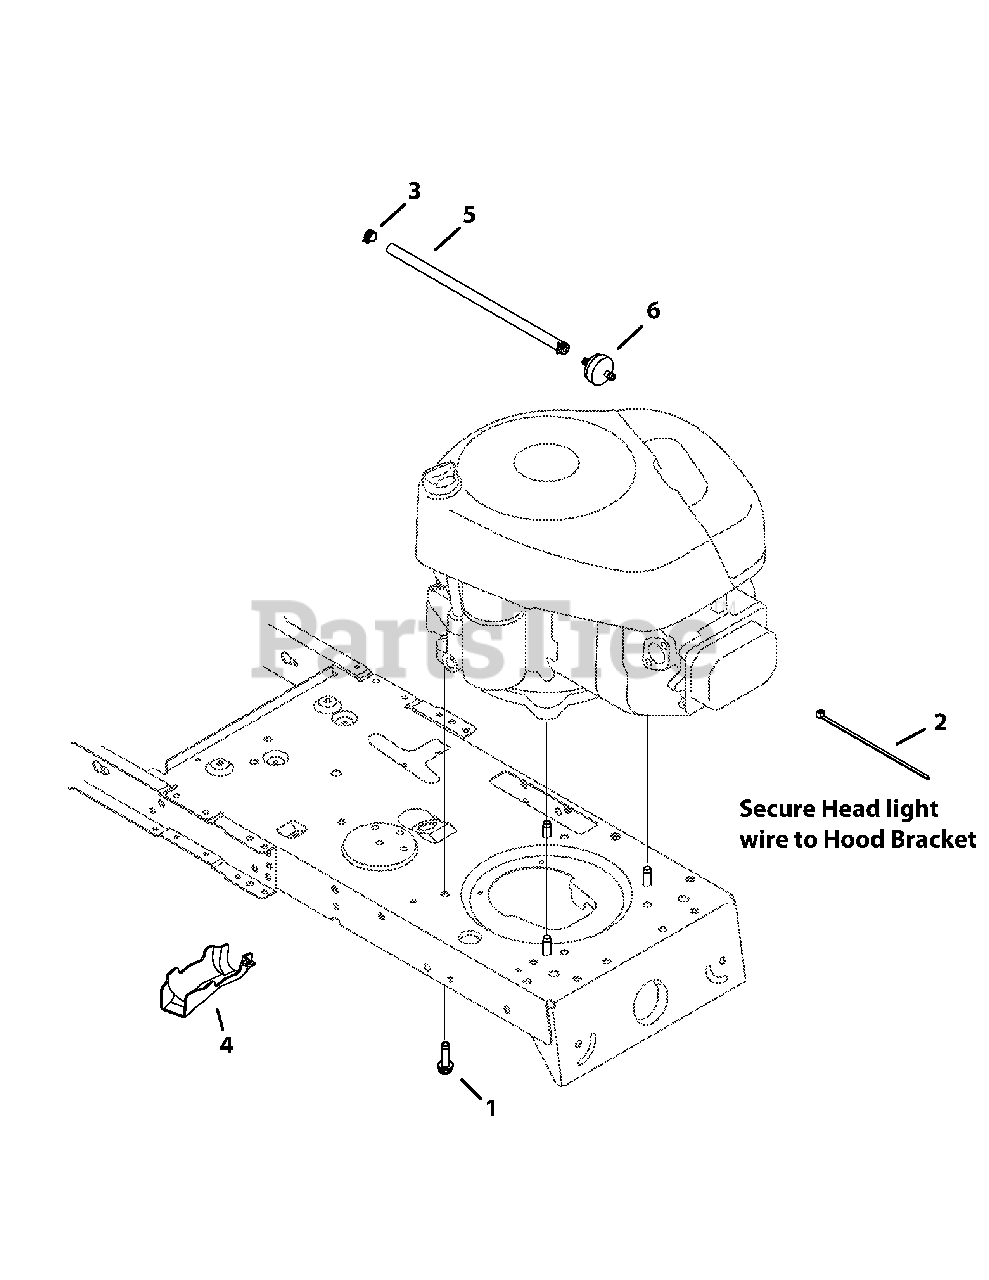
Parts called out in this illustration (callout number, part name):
1	Screw, 3/8-16 x 1.0
2	Cable Tie
3	Clamp Hose, .490 diameter
4	Oil Drain Sleeve
5	Fuel Hose, Low Permeation
6	Fuel Filter
